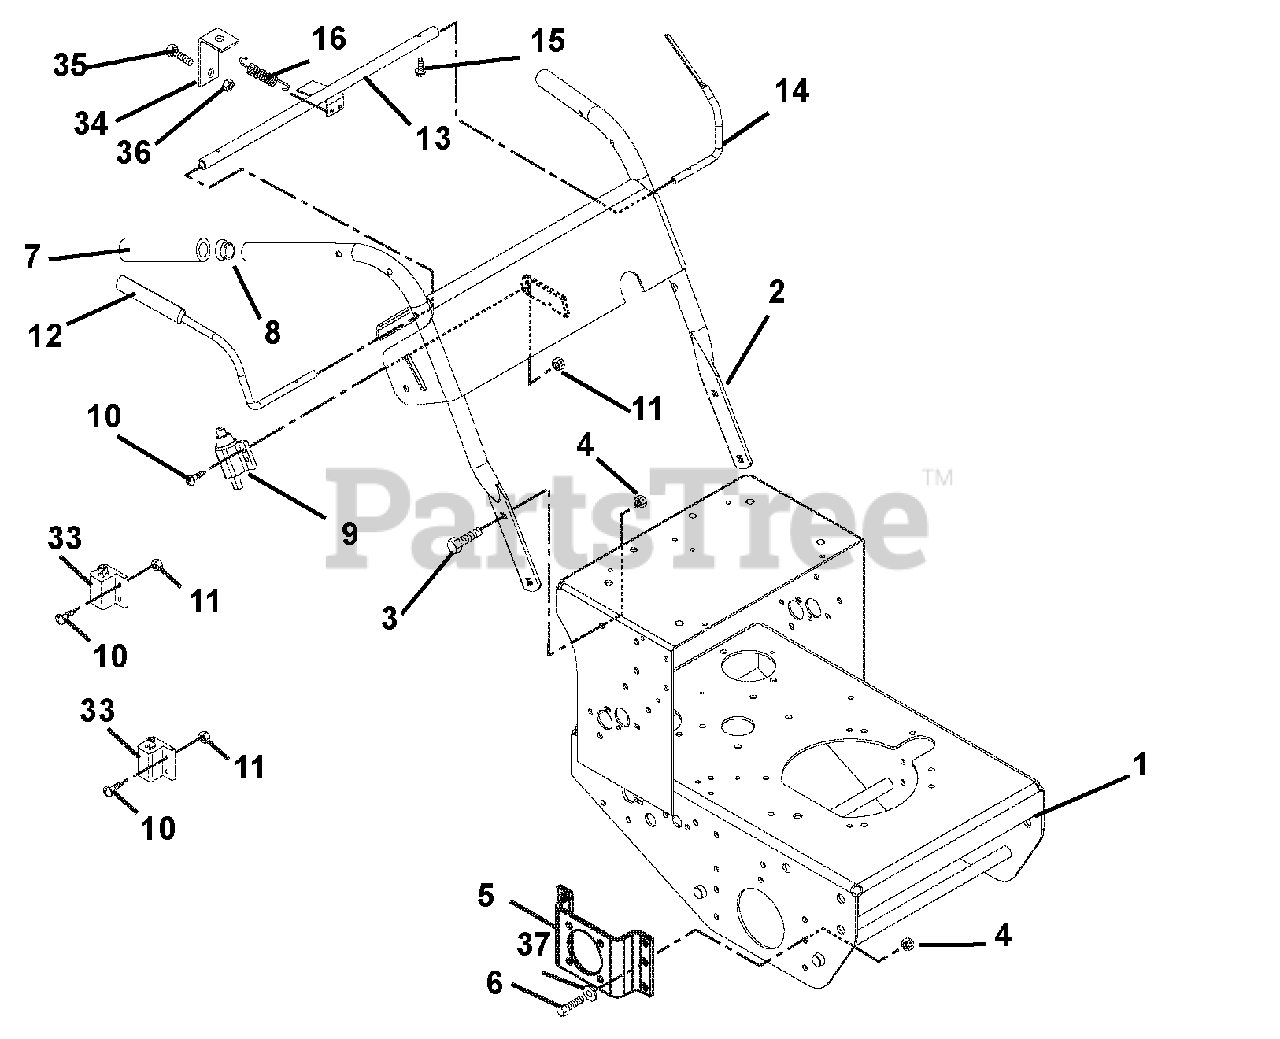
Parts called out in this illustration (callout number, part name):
1	Kit-Frame with Decals
2	Kit-Handlebar with Decals HR15 (105, 106)
3	Bolt-Hex .38-16 x 1.00 Grade 5
4	Nut-Locking-Nylon .38-16
5	Bracket, Wheel Motor Left Hand (105, 108, 120)
6	Bolt-Hex .38-16 x 1.00 Grade 5
7	Grip, Handlebar (105, 106, 108, 109)
8	Caplug, Handlebar (105, 106, 108, 109)
9	Switch, Double Pole (105, 106, 108, 109)
10	Screw, Machine 10-24 x .75 Hex Washer Head (105, 106, 108, 109)
11	Nut-Locking-Nylon 10-24 with Insert (105, 106, 108, 109)
12	Lever, Right Hand-Operator Presence (105, 106, 108, 109)
13	Weldment, Pivot Tube (105, 106, 108, 109)
14	Lever, Left Hand-Operator Presence (105, 106, 108, 109)
15	Screw-Tapping 8-32 x .50 Hex Washer Head (105, 106, 108, 109)
16	Spring-Tension .047 x .438 x 1.45 (105, 106, 108, 109)
33	Switch- Double Pole N.O./N.O. (105, 106, 108, 109)
34	Bracket, Brake Link (105, 106, 108, 109)
35	Bolt, Hex .25-20 x .75 Grade 5 (105, 106, 108, 109)
36	Nut, Locking Nylon .25-20 (105, 106, 108, 109)
37	Washer, Flat Steel .406 x .812 x .065 (105, 106, 108, 109)
